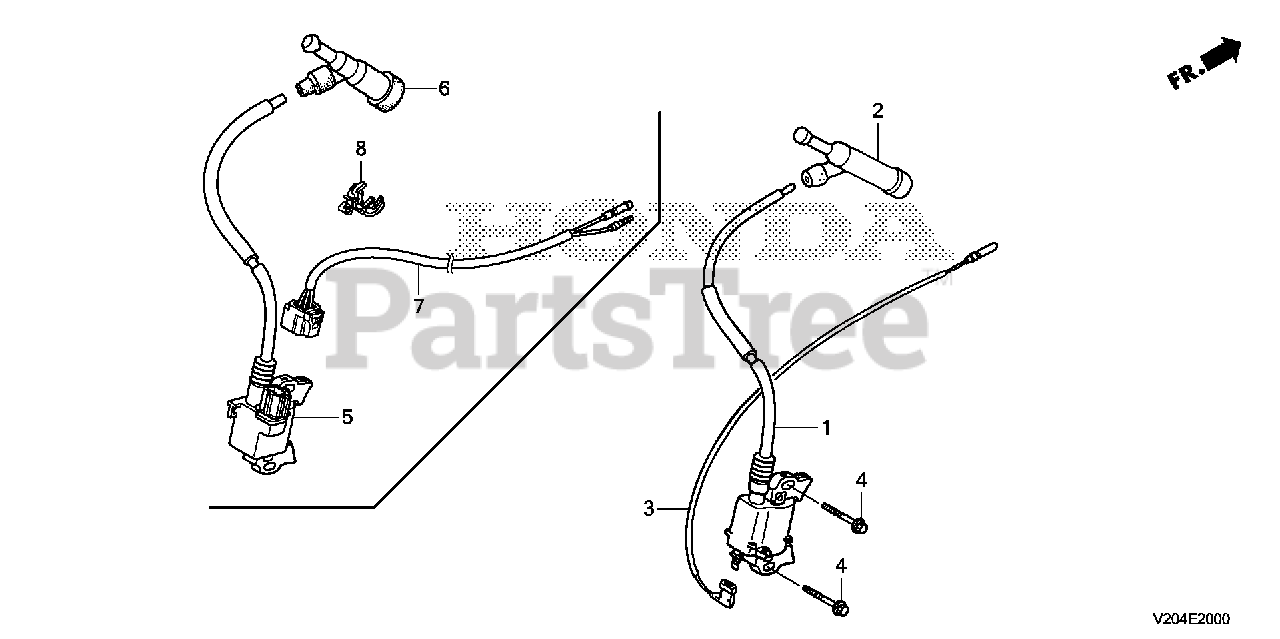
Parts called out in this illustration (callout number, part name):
4	BOLT, FLANGE (6X28) (CT200)
5	COIL ASSY., IGNITION
6	CAP ASSY., NOISE SUPPRESSOR (NGK Y-EZD)
7	WIRE HARNESS ASSY., ENGINE
8	CLIP, HARNESS
